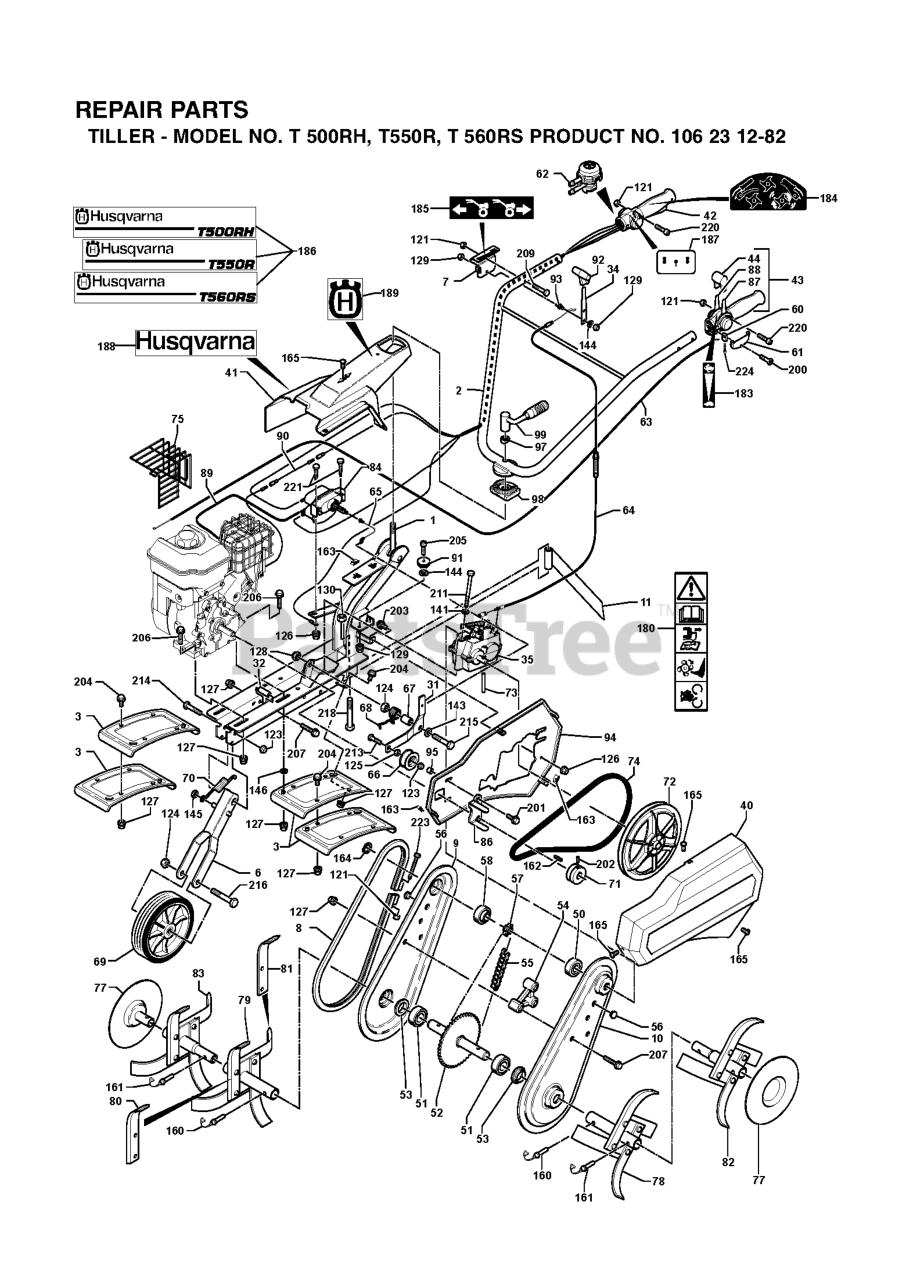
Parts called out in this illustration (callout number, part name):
31	ARM
55	DRIVE CHAIN
69	WHEEL
121	Blocking nut M 6 Z
164	RETAINING RING
